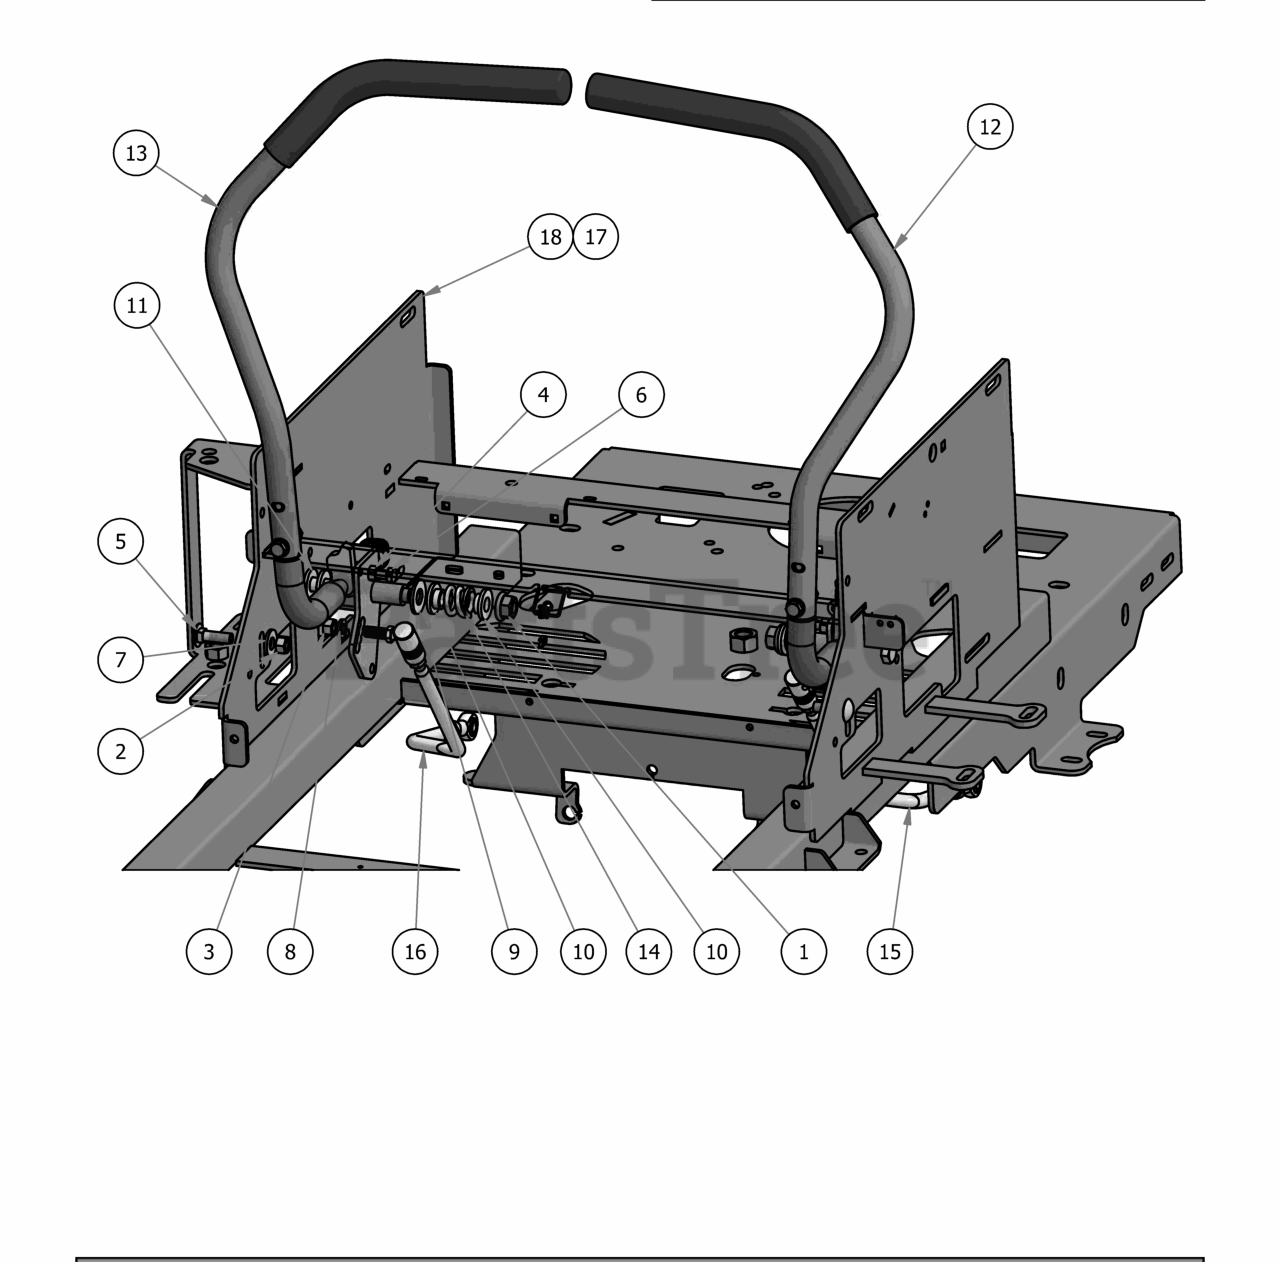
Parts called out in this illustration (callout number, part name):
1	1/2-13 Mechanical Lock Nut
2	3/8" Hex Nut
3	3/8" Fine Threaded Jam Nut
5	3/8" x 1 1/4" Carriage Bolt
6	5/16" x 3/4" Hex Bolt
7	3/8" Flat Washer
8	3/8" Lock Washer
9	1/2" Washer (Grade 8)
10	.515 ID Nylon Shoulder Washer
11	.505 Nylon Spacer
12	2017 MZ Magnum LH Steering Arm
13	2017 MZ Magnum RH Steering Arm
14	Drive Lever Spring
15	Push Rod-Right
16	Push Rod-Left
17	2017 MZ/ZT 54"-60" Frame
18	2017 MZ/ZT 42"-48" Frame
